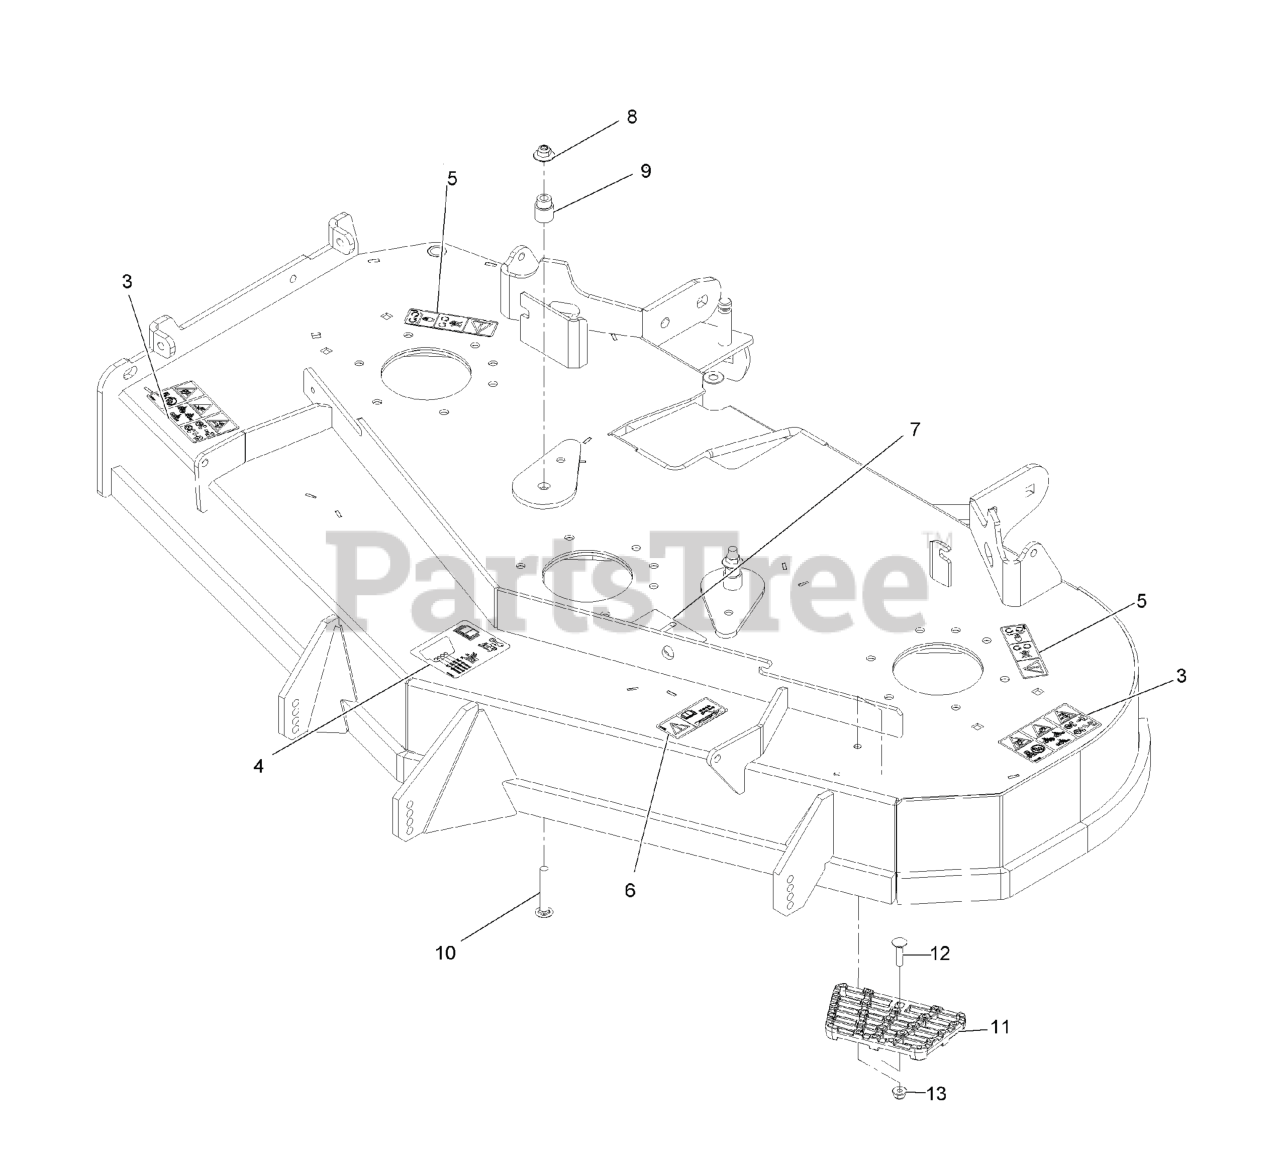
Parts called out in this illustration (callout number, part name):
3	DECAL-DANGER THROWN OBJECTS
4	DECAL-ROLLER, ANTI-SCALP
5	DECAL-COVER, MISSING
6	DECAL-TORQUE, BOLT
7	DECAL-BELT ROUTING
8	Nut-Nyloc 3/8-16 Flg
9	BUSHING-IDLER
10	SCREW-CARR
11	STEP-DECK
12	Bolt-Carriage 5/16-18 X 1 1/4
13	NUT-HF, NI
